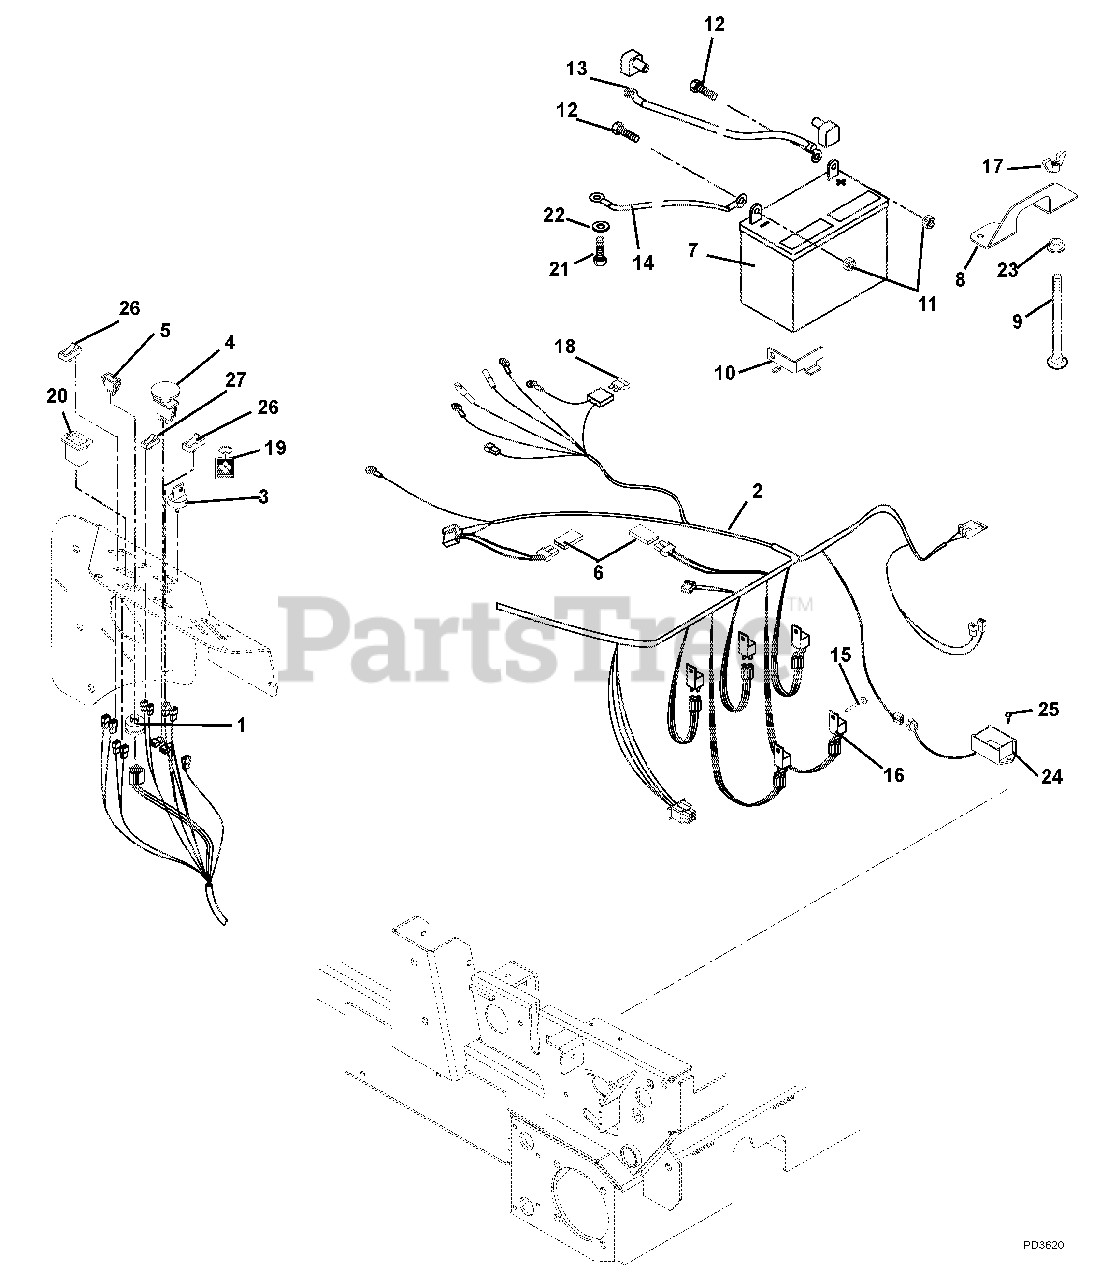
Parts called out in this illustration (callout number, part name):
1	Key Switch
2	Harness, Rapid XD
3	Key with Shield
4	Switch, Clutch With Retainer Ring
5	Light, Indicator
6	Diode, Connector Shell
8	Hold Down, Battery
9	Bolt, Round Head Square Neck .25-20 x 7.50
10	Bracket, Battery Position
11	Nut, .25-20 Nyloc Flange
12	Bolt, Hex .25-20 x .75 Grade 5
13	Cable, Positive
14	Cable, Negative Battery 35.0"LG
15	Rivet, Nylon
16	Relay, Sealed with diode (Included with Harness)
17	Nut, Locking Wing .25-20
18	Fuse, 30 Amp (Included with Harness)
19	Key Chain
20	Hour Meter
21	Bolt, Hex M8 x 1.25 x 16
22	Washer, Locking .31 x .078 Regular
23	Nut, Push .25 x .50 O.D.
24	Assembly, Weight Transfer Angle Sensor
25	Screw, Tapping 12-24 x .50 Hex Washer Head Thread Rolling
26	Switch, Double Pole Double Throw
27	Switch, 2 Pole/Rocker
